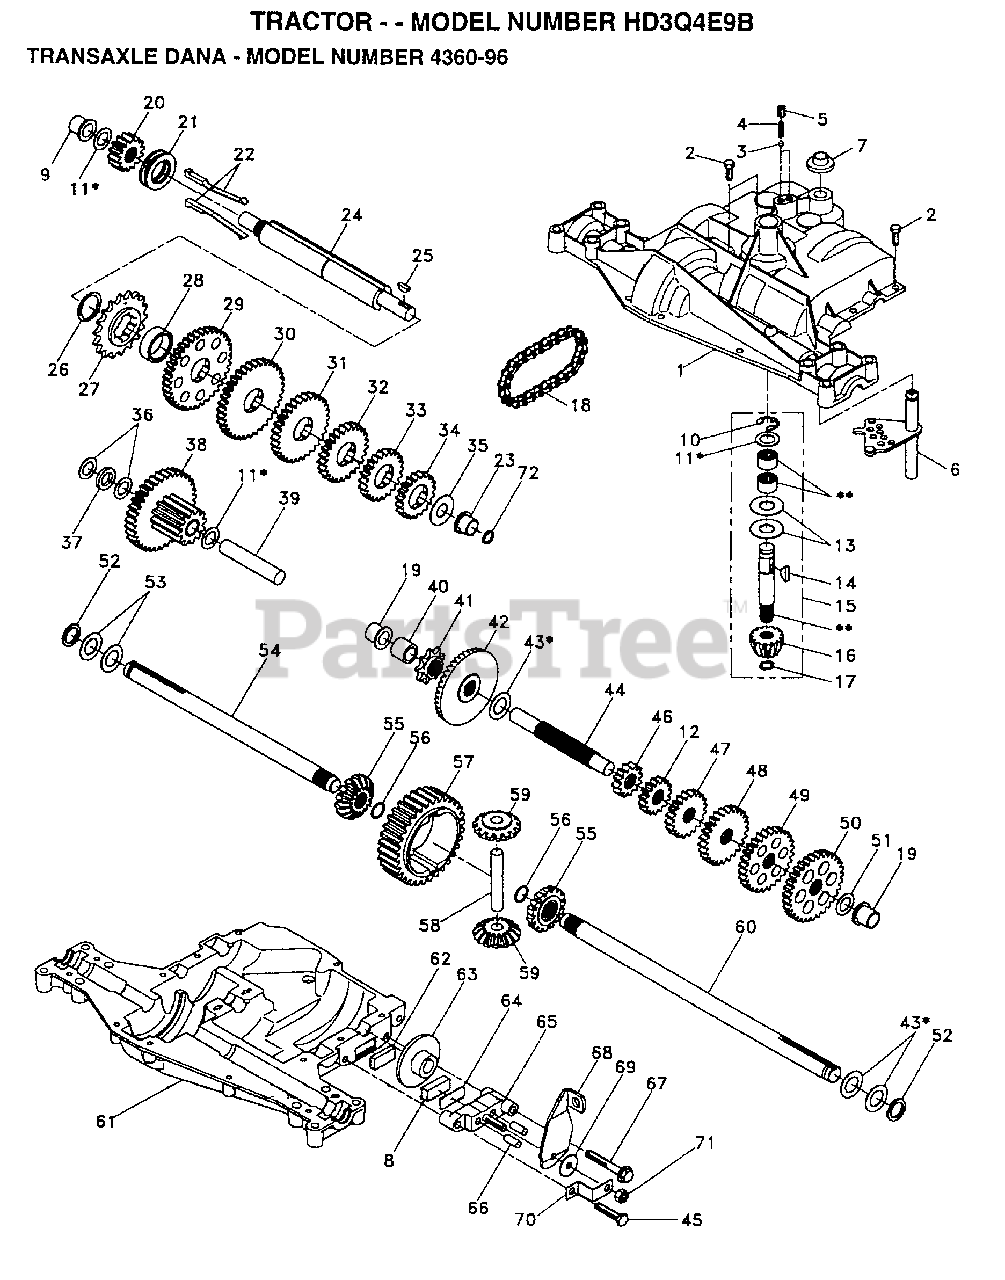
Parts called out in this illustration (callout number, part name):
1	HARNESS.IGNITION
4	"SPRING, DETENT LT"
5	"SCREW, SET LT"
6	KIT SHIFTER ASM
7	SHIFTER BOOT
8	PUCK T
10	RETAINING RING LT
11	ASM KIT SHIM 4689
12	PLUG.PLASTIC
13	WASHER T
14	KEY WOODRUFF-DANA
17	"RING,RETAINING LT"
18	"CHAIN,24 PTCH LT"
19	BEARING.FLNG.5510
20	GEAR SPUR 14 TTH
21	CLUTCH.COL.5467
22	KIT.ASM.CLUTCH KY
23	BEARING.FLNG.5511
24	SHAFT INTERM DANA
25	WOODRUFF KEY
26	"RING,RETAINING LT"
27	SPROCKET 18T T
28	SPACER YT
29	GEAR SPUR 37 TTH
30	GEAR SPUR 35 TTH
31	GEAR SPUR 30T
32	GEAR 25T LT
33	GEAR SPUR 22 TT
34	SPUR GEAR 19T
35	"WASHER, PLAIN LT"
36	WASHER 025
37	SPACER
38	ASSM GEAR COMB
39	SHAFT IDLER
40	SPACER T
41	SPROCKET 9T LT
43	ASM KIT SHIM
44	SHAFT T
45	"SCREW, TAPPING LT"
46	GEAR SPUR 12 TTH
48	"GEAR, SPUR 25T LT"
49	GEAR 28T T
50	"GEAR, SPUR 31T LT"
51	WASHER 060
52	NEOPRENE WASHER
53	WASHER 031
55	GEAR 15T T
56	"RING,RETAINING LT"
58	SHAFT T
59	GEAR 1ST T
61	HOUSING LOWER TNS
62	PUCK T
63	BRAKE DISC. T
64	SPACER LT
66	PIN T
69	WASHER LT
71	NUT.LOCK.5/16-24
72	SEAL.OIL.DAN.5508
